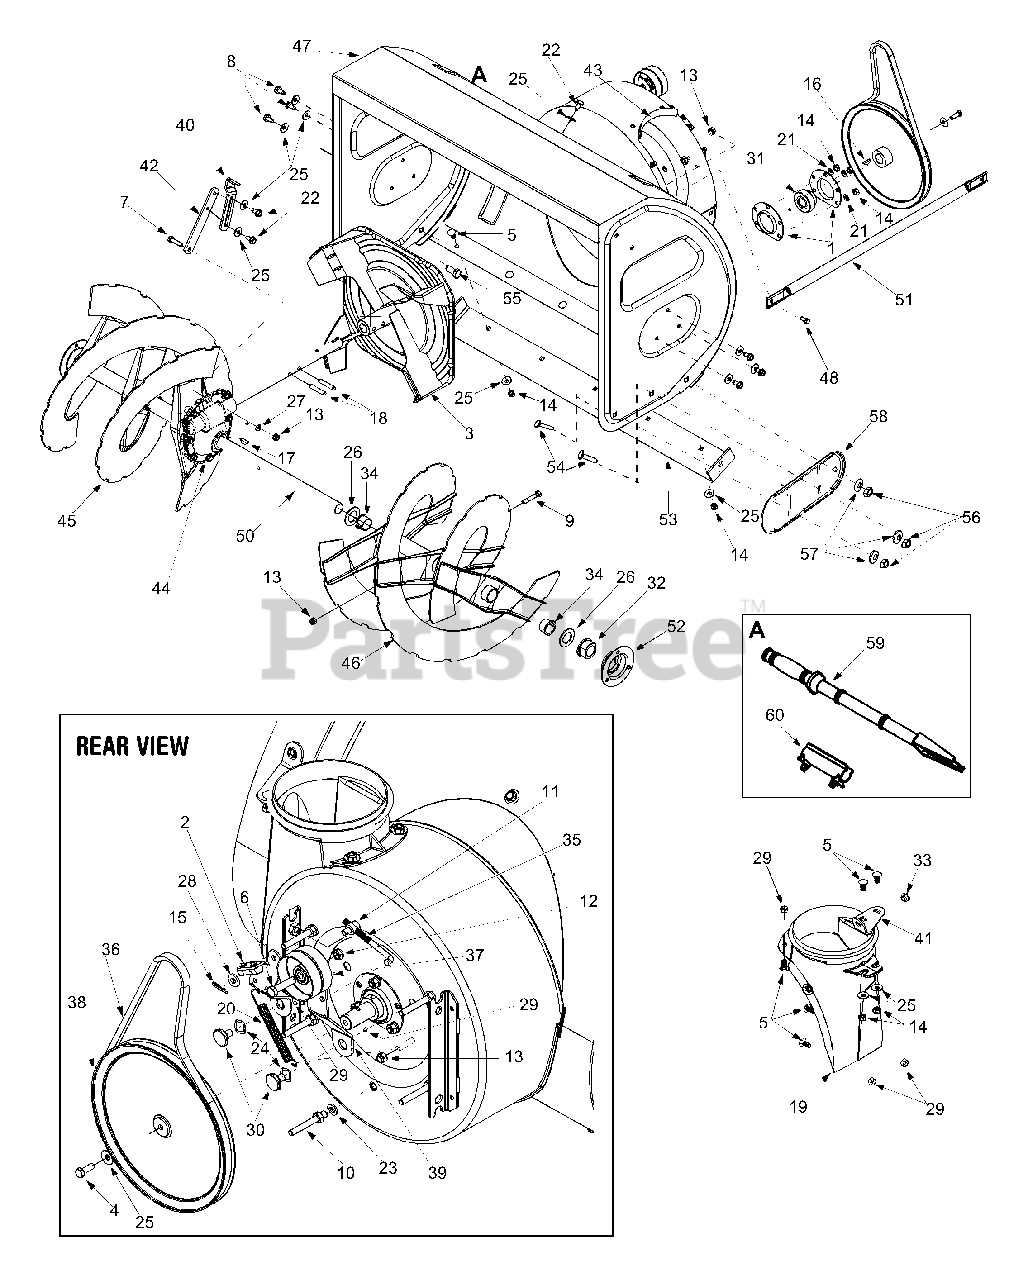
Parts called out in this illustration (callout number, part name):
1	Bearing Housing
2	Auger Brake Bracket Assembly
5	Carriage Bolt 5/16-18 x .750"
6	Hex Screw, Special 3/8-24 x 1.5"
7	Hex Screw 5/16-18 x 1.25"
8	Self-Tapp. Screw 5/16-12 x.750"
9	Shear Bolt 5/16-18 x 1.75"
11	Ferrule
12	Jam Nut 3/8-24
13	Hex Lock Nut 5/16-18
14	H ex Nut 5/16-18
15	Hairpin Clip
18	Spiral Pin
19	Chute Adapter
20	Extension Spring
21	Lock Washer
22	Screw, 5/16-18 x.75
23	Lock Washer
24	Wave Washer
25	Belleville Washer
26	Flat Washer
27	Spring Washer
28	Flat Washer
29	Flange Lock Nut 5/16-18
30	Shoulder Screw
31	Self-Aligning Bearing
32	Flange Bearing w/ Flats
33	Plastic Bushing
34	Flange Bushing
35	Auger Idler Rod
36	V-Belt
37	Flat Idler
38	Pulley
50	Spiral Axle
54	Carriage Screw
55	Carriage Bolt
56	Hex Nut 3/8-16
57	Bell Washer
59	Chute Clean-Out Tool
60	Tool Mount
